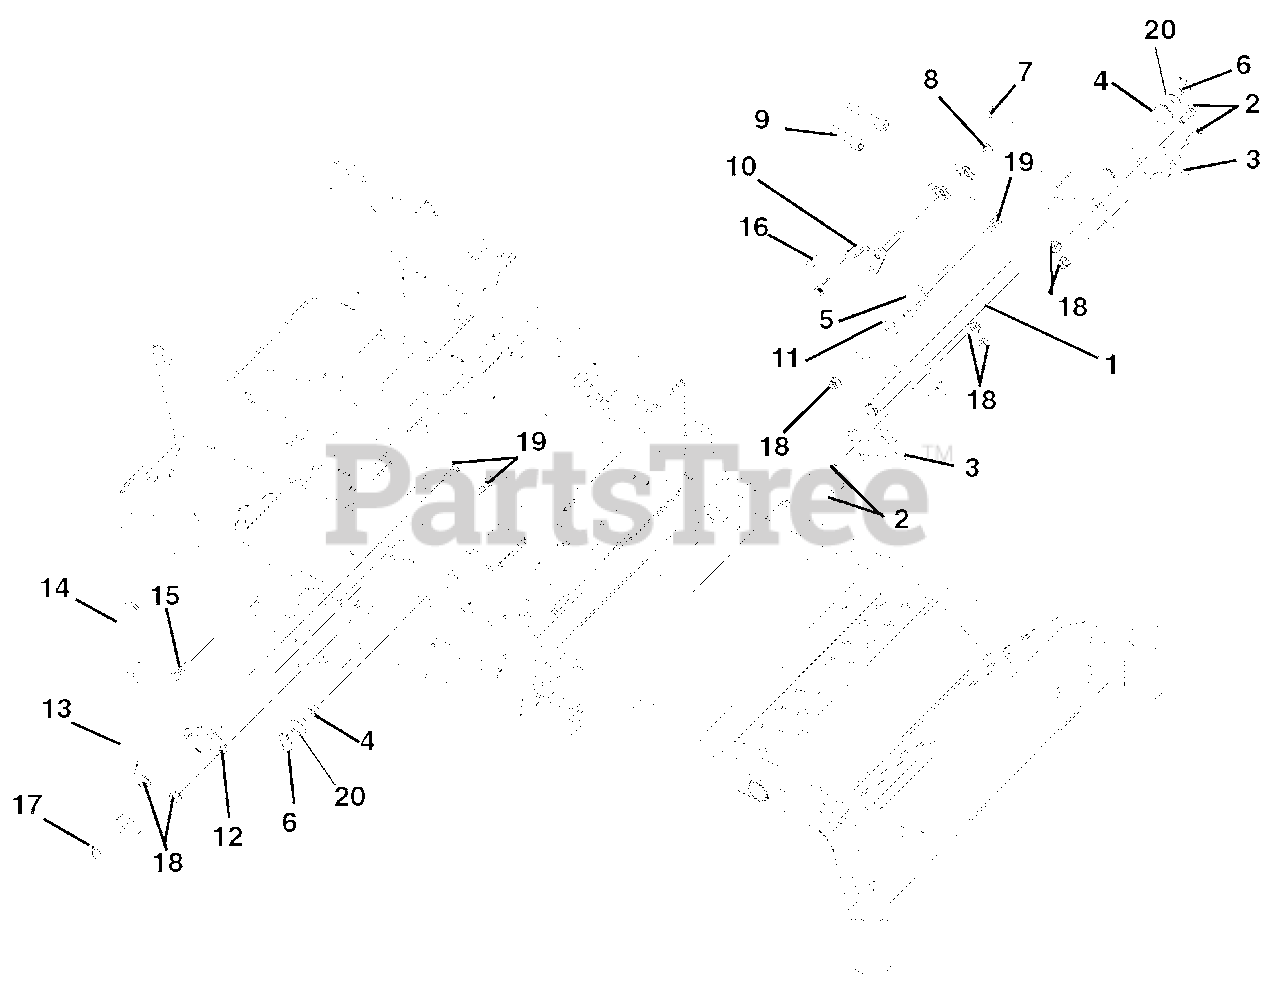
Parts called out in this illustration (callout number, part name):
1	WMT, NEUTRAL INTERLOCK
2	@BLT-RDHDSQNK .31-18X1.00 G5YZ
3	NEUTRAL LOCK LATCH - BLACK
4	BSHG-FLG .750X1.000X.625X1.250
5	PLATE, NEUTRAL INTERLOCK
6	RG-RTNG-EXT .689X.078
7	PIN-HAIR INT .06X.18X.77
8	@WSHR-FL-STL.344X.688X.065YWZC
9	CABLE, BRAKE ACTUATING
10	WMT, PARK BRAKE ARM
11	BSHG, FLG .325X.499X.26X.88
12	BUSHING, FLANGED
13	WMT - PARKING BRAKE ARM
14	GRIP, PARKING BRAKE (YELLOW)
15	@SCR-TAP .38-16X1.00 HWH TR YZ
16	KEY-WDRF .13X.63 HRD#5
17	RG-RTNG-EXT .500X.050 (SNAP)
18	@NUT-LK-NYL-FLG .31-18 YWZC
19	@BLT-HEX .31-18X1.00 GR5 YWZC
20	WSHR-FL-STL .812X1.370X.10 YWZ
